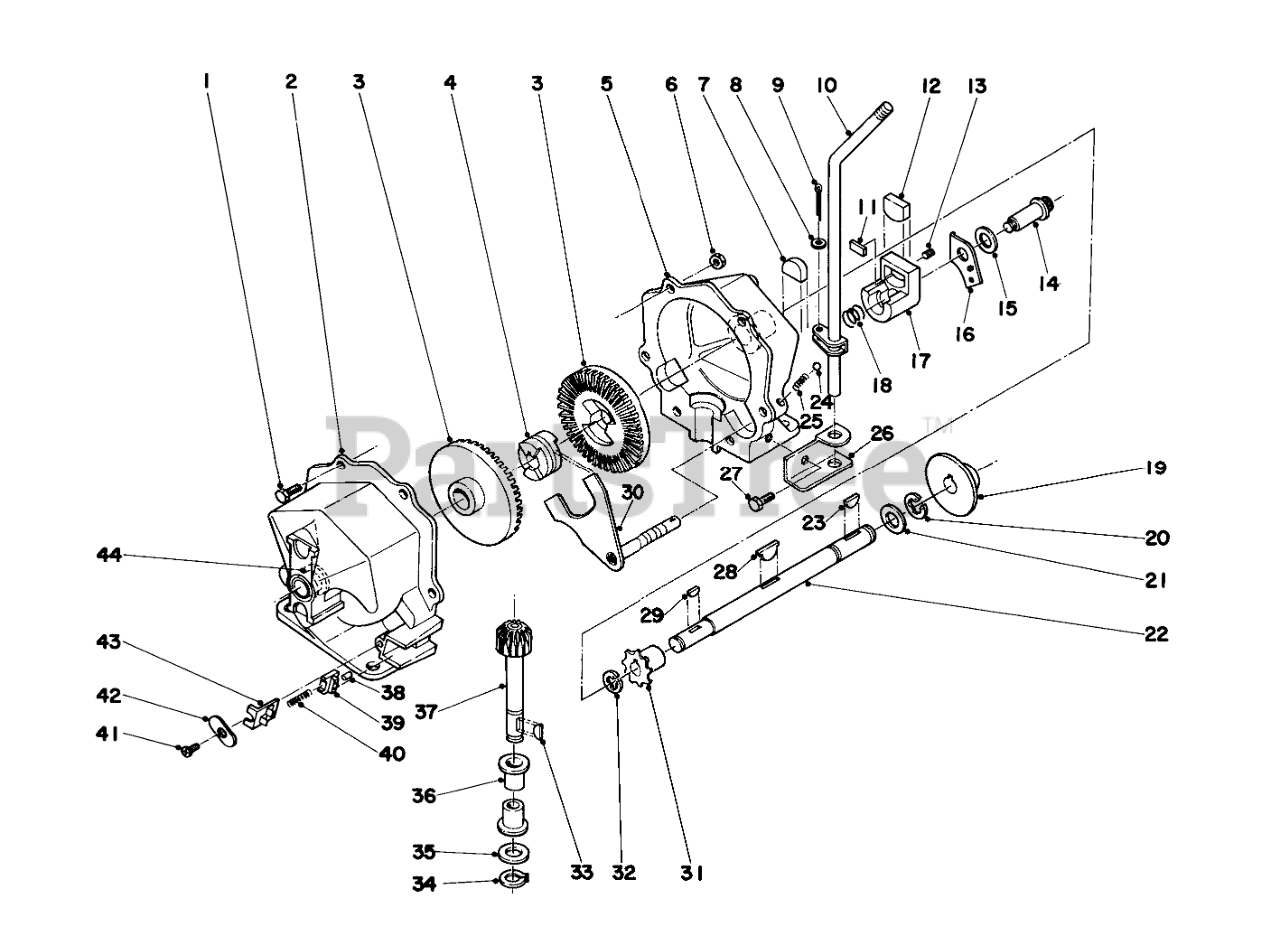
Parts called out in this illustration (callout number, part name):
1	Bolt Hex Head
2	Housing (Incl. Ref. #44)
3	Bevel Gear
4	Clutch Collar
5	Housing (Incl. Ref. #44)
6	Locknut
7	FRICTION PUCK
8	Plain Washer
9	Cotter Pin
10	Shift Lever
11	Spacer
12	FRICTION PUCK
13	Set Screw
14	Shoulder Bolt
15	Washer Kit
16	Actuating Lever
17	Brake Jaw
18	Compression Spring
19	BRAKE DISC
20	RETAINING RING
21	Washer Kit
22	Output Shaft
23	Woodruff Key
24	Ball Detent
25	Detent Spring
26	Shift Lever Bracket
27	Hex Head Bolt
28	Hi Pro Key
29	Woodruff Key
30	Detent Shaft
31	Sprocket
32	Retaining Ring
33	Woodruff Key
34	RING-Retaining
35	Plain Washer
36	Flange Bearing
37	Input Shaft
38	Actuating Pin
39	Carrier Contact Assem.
40	Compression Spring
41	Self Tapping Screw
42	Terminal Retainer Board
43	Terminal Board
44	Bearing Flange
